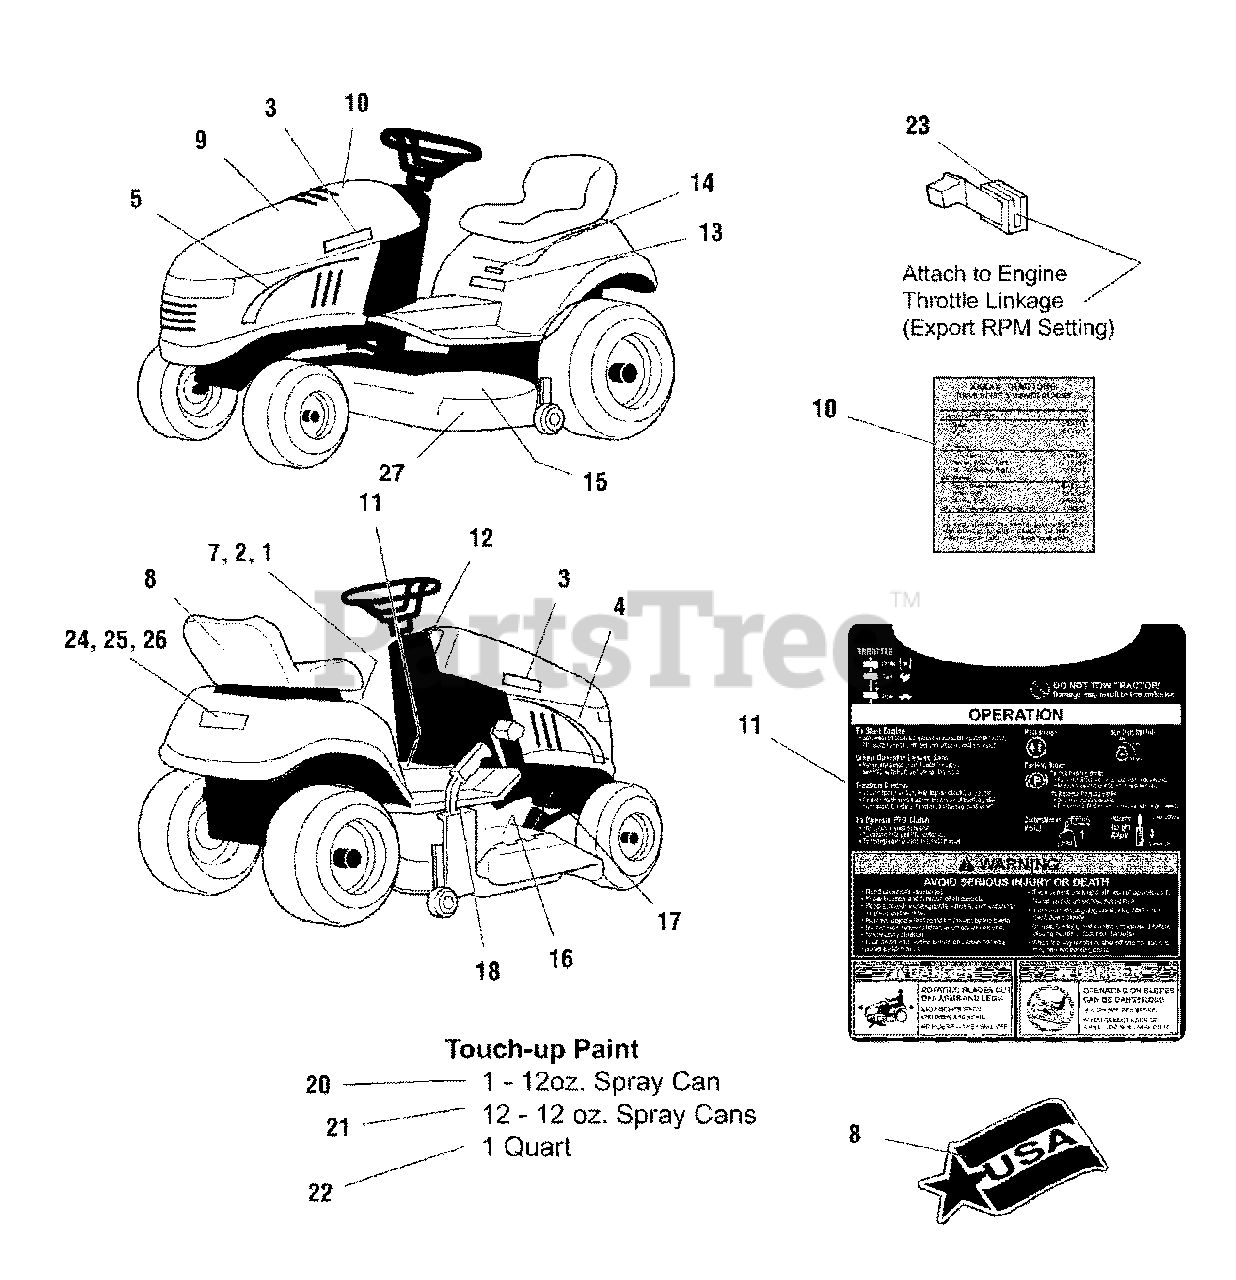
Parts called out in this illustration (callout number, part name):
1	DECAL, Express
2	DECAL, Shift Pattern
2	DECAL. Shift Pattern
3	DECAL, Express Hood Logo
4	DECAL, R.H. Hood Stripe
5	DECAL, L.H. Hood Stripe
7	DECAL, Release Valve
7	DECAL, 1415 - AGCO Allis
7	DECAL, 1416 - AGCO Allis
7	DECAL, 1417 - AGCO Allis
8	DECAL, Logo, USA
9	DECAL, Touch Up Paint
10	DECAL, Belt & Blade
11	DECAL, Operating Instructions
11	DECAL, Operating Instructions, Icon Based
12	DECAL, PTO Control
13	DECAL, Simplicity Logo
14	DECAL, Model
15	DECAL, Danger, Rotating Cutting Blade
16	DECAL, Danger, Chute in Place
17	DECAL, Cutting Width, 38"
17	DECAL, Cutting Width, 44"
18	DECAL, Height of Cut
20	TOUCH-UP PAINT, Cardinal Red, 1-12oz Spray Can
21	TOUCH-UP PAINT, Cardinal Red, 12-12oz Spray Cans
22	TOUCH-UP PAINT, Cardinal Red, 1-1qt Can
23	STOP, Throttle
24	DECAL, Decibel, Export Only
25	DECAL, CE, Export Only
26	DECAL, POWER MASS, (1693641 & 1693670 Only)
27	DECAL, Free Floating Mower
